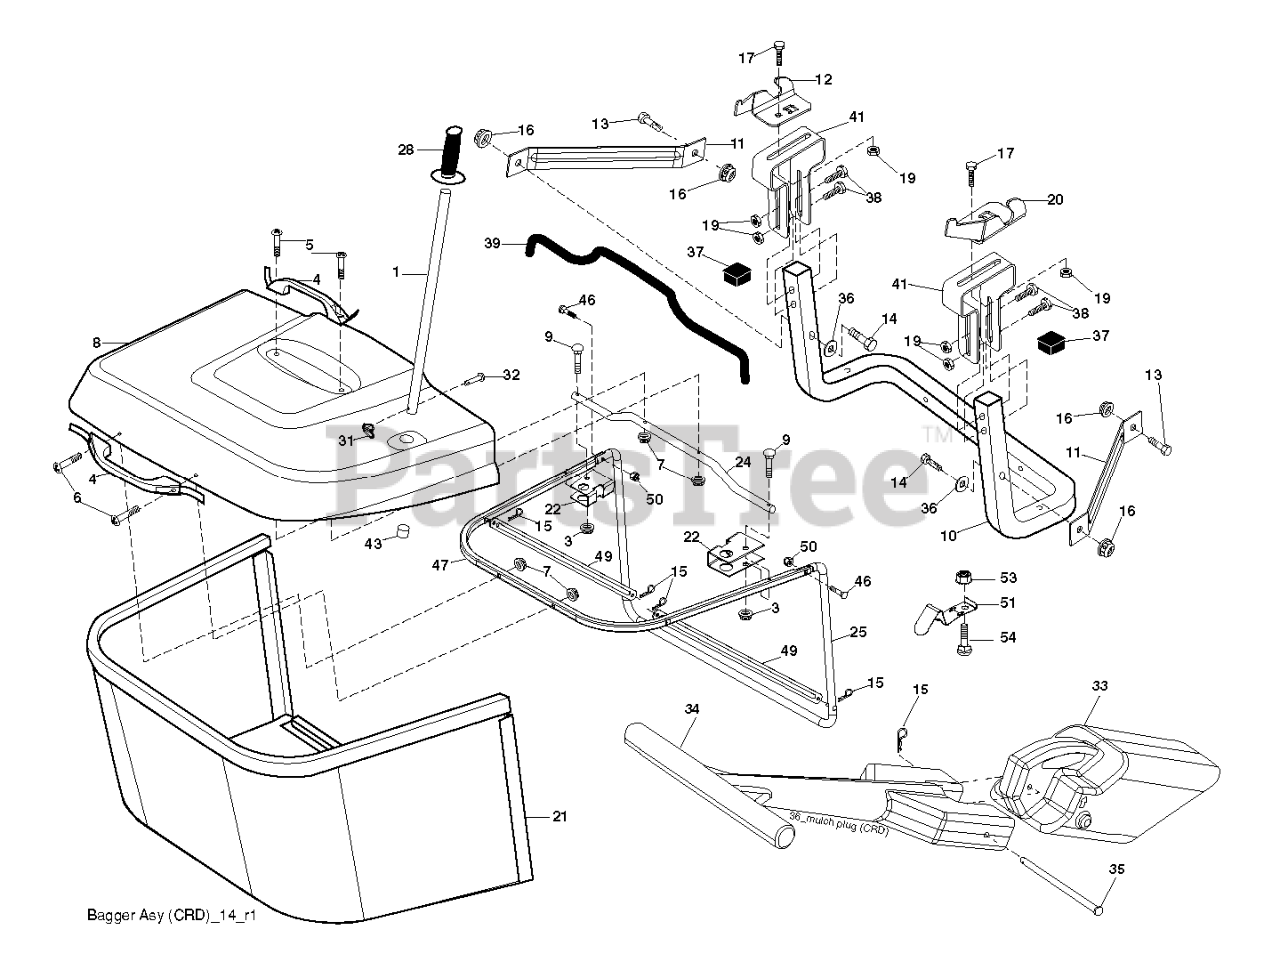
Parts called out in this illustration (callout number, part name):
1	TUBE.HANDLE.BAGGER.CRD/SRD.BLA
3	NUT T
4	HANDLE.BAGGER.W/LVRS.BLK.CRD
5	SCREW.PAN.HEAD
6	REPL BY 532 75 00-29
8	COVER.PNT.BGR.CRD.WSLOTS.MS668
9	Bolt Carriage 1/4-20 x 2.25d x Gr.5
10	TUBE
11	BRACKET.SUPPORT.UPPER.BAG.CRD
12	BRKT PIVOT
14	BOLT-HEX EAK
15	RETAINER-SPRNG RB
16	NUT LOCK FLG 3/8-16 UNC
17	RP BOLT 5/16-18 X3/4 ZN/YEL GR
19	NUT LOCK HEX FLANGE 5/16-18
20	BRKT.PIVOT.RH.CRD
21	BAGGER.ASM.CRD.2007
22	BRACKET.BAGGER.SD.ELECTRIC.CRD
24	TUBE.PIVOT.BAG.CRD.BLACK
25	PIPE
28	GRIP.HANDLE.BLACK
31	RETAINER CLIP
32	RIVET,DRILLED
33	MULCHING.PLUG.107.CRD.(2 2)
34	HANDLE.MULCHER.92.CRD (2 2)
36	WASHER
37	Plug Support Bagger CRD
38	BOLT.5/16-18X2.5
39	SEAL.BAGGER.CRD
41	BRACKET.BAGGER.SD.ELECTRIC.CRD
43	PLUG, TUBING END
46	BOLT.CARRIAGE.5/16-18
47	PIPE
49	ROD
50	NUT.71038.31-18.HEX.NYLOCK
51	LATCH
53	NUT
54	BOLT
